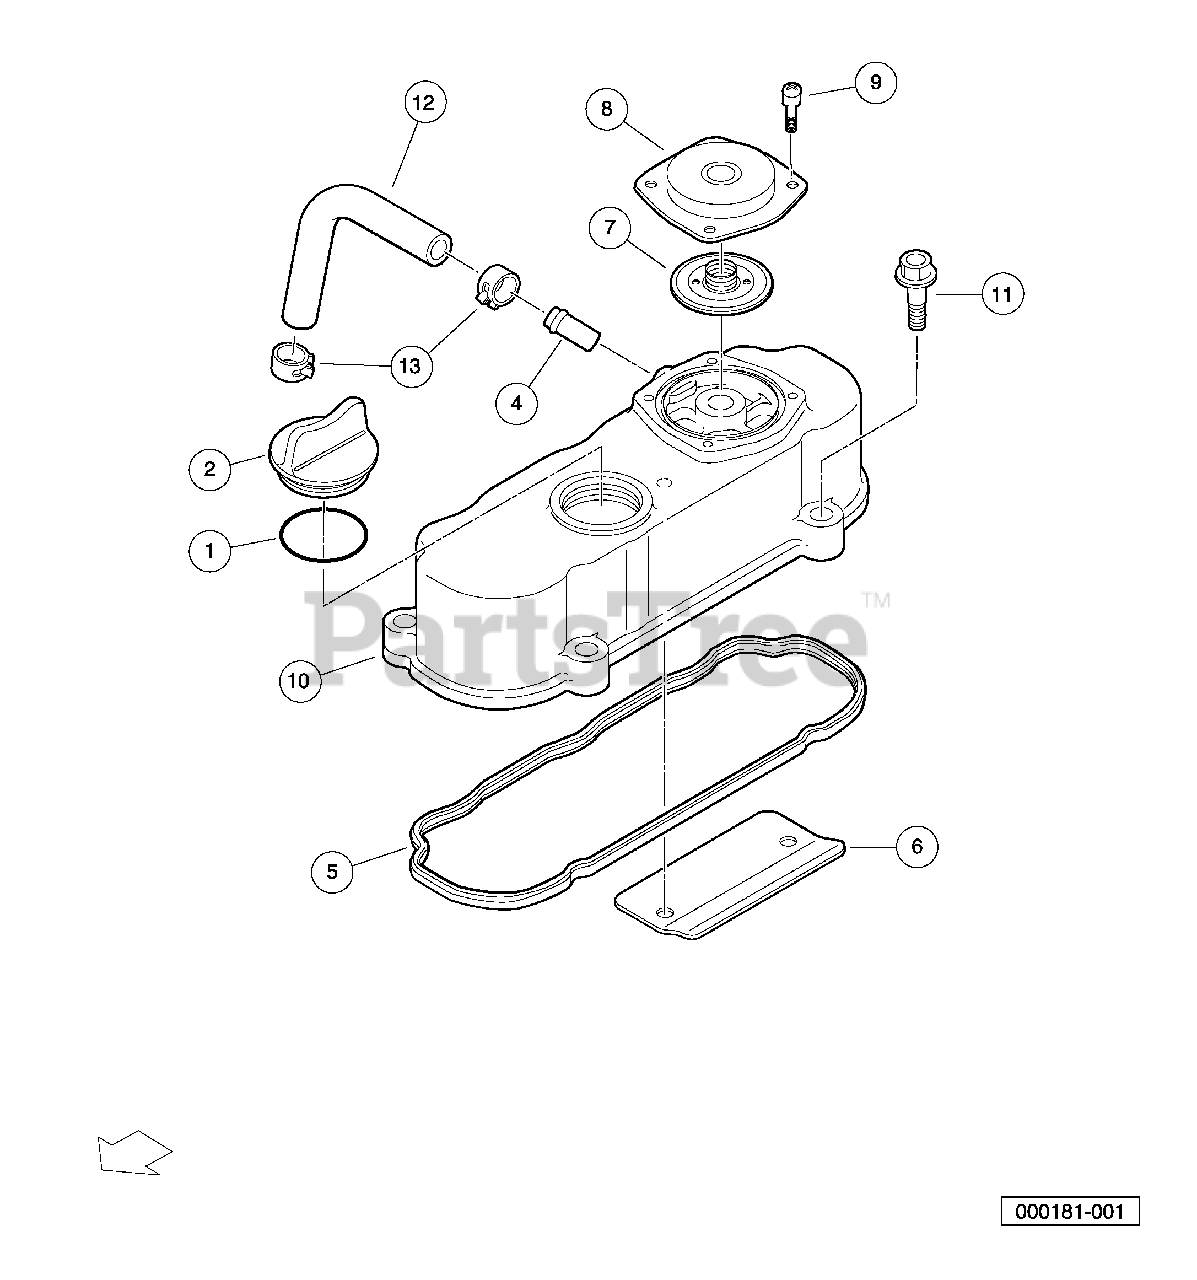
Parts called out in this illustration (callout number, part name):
1	O Ring, 30 X 36
2	Plug, Oil Filler
3	Assembly, Cylinder Head Cover
4	Pipe, Water Return, D722
5	Gasket, Cylinder Head Cover
6	Shield, Breather
7	Valve, Breather
8	Cover, Breather
9	Screw, Breather
10	Cover, Cylinder Head
11	Bolt, Cylinder Head Cover
12	Tube, Breather
13	Clamp, Breather Tube
